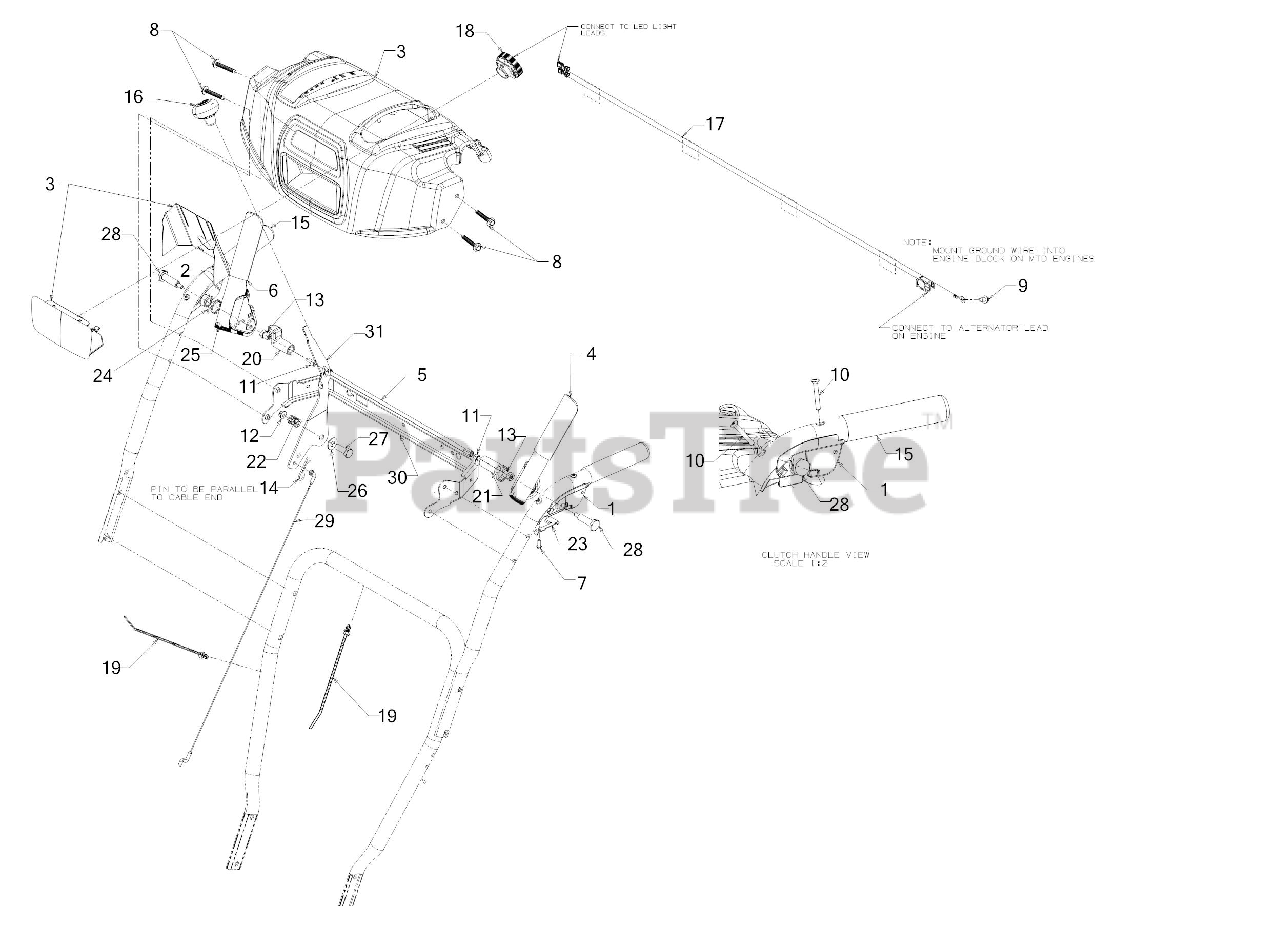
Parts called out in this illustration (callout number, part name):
1	CLUTCH LOCK HANDLE ASSEMBLY (LH)
1	HEX NUT
2	CLUTCH LOCK HANDLE ASSEMBLY (RH)
2	HEX NUT
3	HANDLE PANEL ASSEMBLY (CRAFTSMAN)
4	HANDLE ASSEMBLY (LH)
5	PIVOT ROD
6	ENGAGEMENT HANDLE ASSEMBLY (RH) (RED)
7	SCREW #8-16 x .50
8	SCREW 1/4-20 x 1.625
9	SCREW 1/4-20 X.500
10	SCREW #10-24 x 1.375
11	SCREW 1/4-20 x .50
12	FLANGE LOCK NUT
13	HEX NUT W/PATCH
14	INTERNAL COTTER PIN
16	SHIFT KNOB
17	HARNESS
18	HEADLIGHT ASSEMBLY
19	PUSH MOUNT TIE
20	LOCK PLATE
21	CLUTCH LOCK CAM
22	COMPRESSION SPRING
23	CLUTCH SPRING
24	TORSION SPRING
25	RUBBER BUMPER
26	FLAT WASHER
27	SHOULDER SCREW
28	SHOULDER SCREW .437 x 1.345 1/4-20
29	SPEED SELECTOR CABLE (PLASTIC)
30	HANDLE SUPPORT BRACKET
31	SHIFT LEVER
